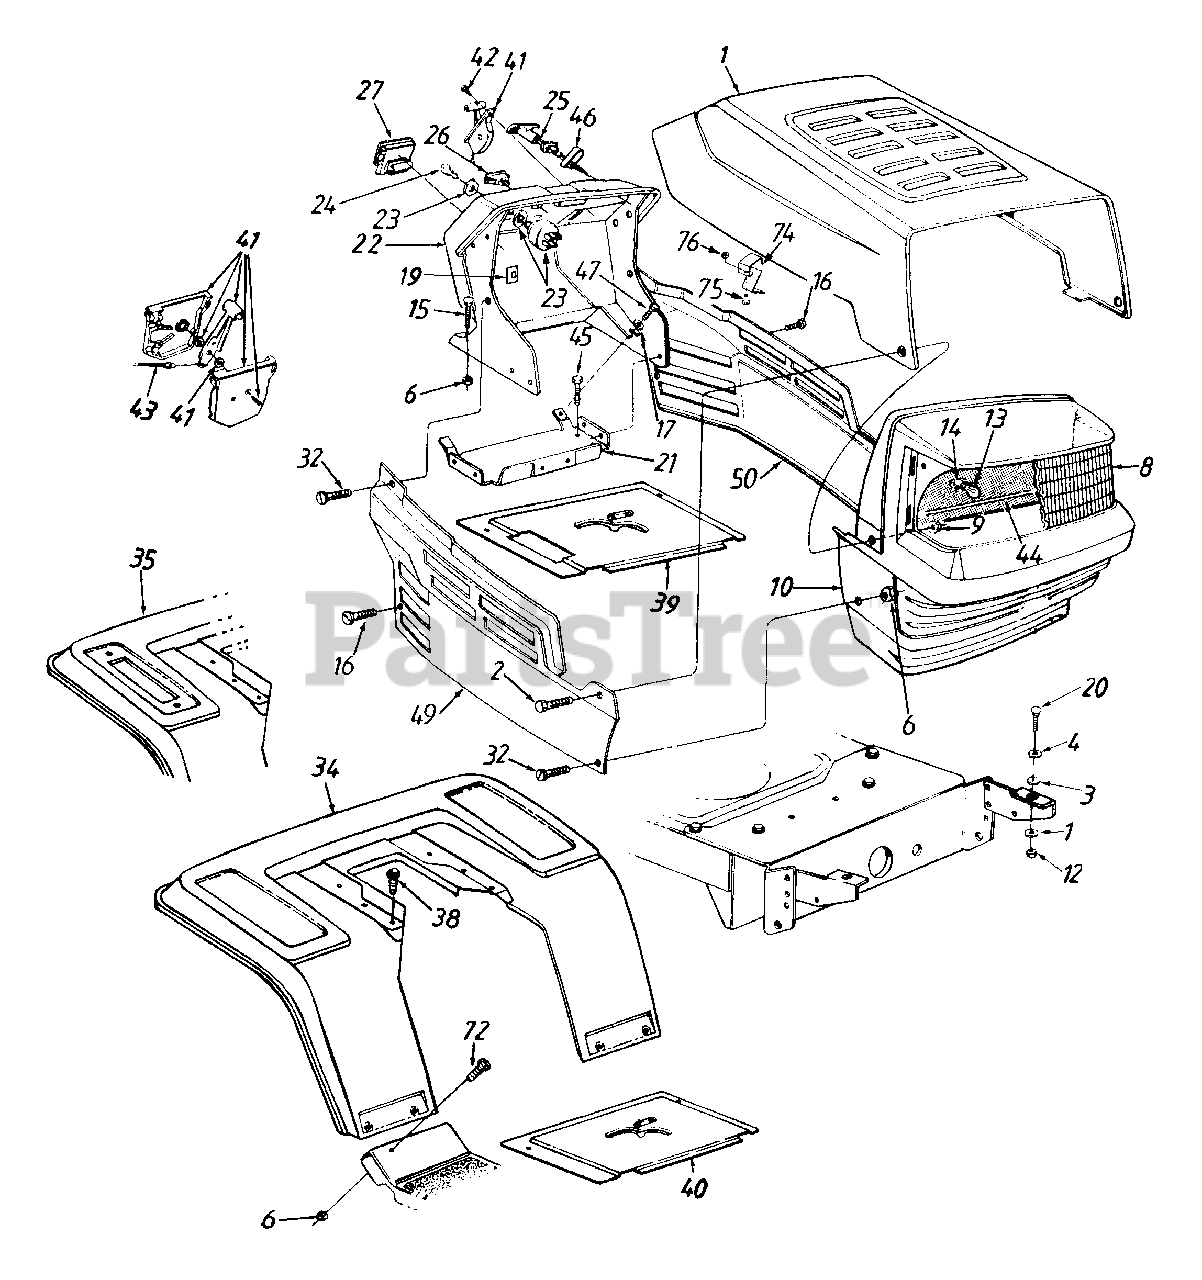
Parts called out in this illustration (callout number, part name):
3	Speed Nut
4	Fl-Wash. .34" I.D. x 1" O.D.
6	Hex Sems Nut 1/4-20 Thd.
8	Headlight Lens w/o Logo
9	Flange L-Nut 1/4-20 Thd.
10	Grille
12	Hex Nut 5/16-18 Thd. (Gr.5)
13	Lamp
14	Socket
15	Carriage Bolt 1/4-20 x .75" Lg.
16	Hex Wash. Hd. TT-Tap Scr. 1/4-20 x .5"
17	Fl-Wash. .281" I.D. x .73" O.D.
19	Speed Nut 1/4-20 Thd.
20	Hex Bolt 5/16-18 x .75" Lg.
23	Ignition Switch
24	Ignition Key
25	Choke Control 23" Lg.
26	Light Switch
27	Ammeter
32	Pan Hd. Scr. 1/4-20 x .75" Lg.
41	Throttle Box Ass'y.
42	Truss Mach. AB-Tap Scr. #10 x .5" Lg.
43	Throttle Control Wire 18.5" Lg.
44	Grille Reflector Label
45	Hex Wash. Hd. B-Tap Scr. 5/16-18
46	Choke Retainer
47	Hex TT-Tap Scr. 1/4-20 x .75" Lg.
74	Hood Latch
75	Truss Mach. Scr. 10-24 x .5" Lg.
76	Hex Sems Nut 10-24 Thd.
17870A-0483	FENDER-RR W/FRAME - CHARCOAL GRAY (0483)
17870A-0498	FENDER-RR W/FRAME - OLD CUB YELLOW (0498)
17870A-0638	FENDER-RR W/FRAME - MTD/TROY-BILT RED (0638)
17870A-0667	FENDER-RR W/FRAME - MIDNIGHT BLUE (0667)
